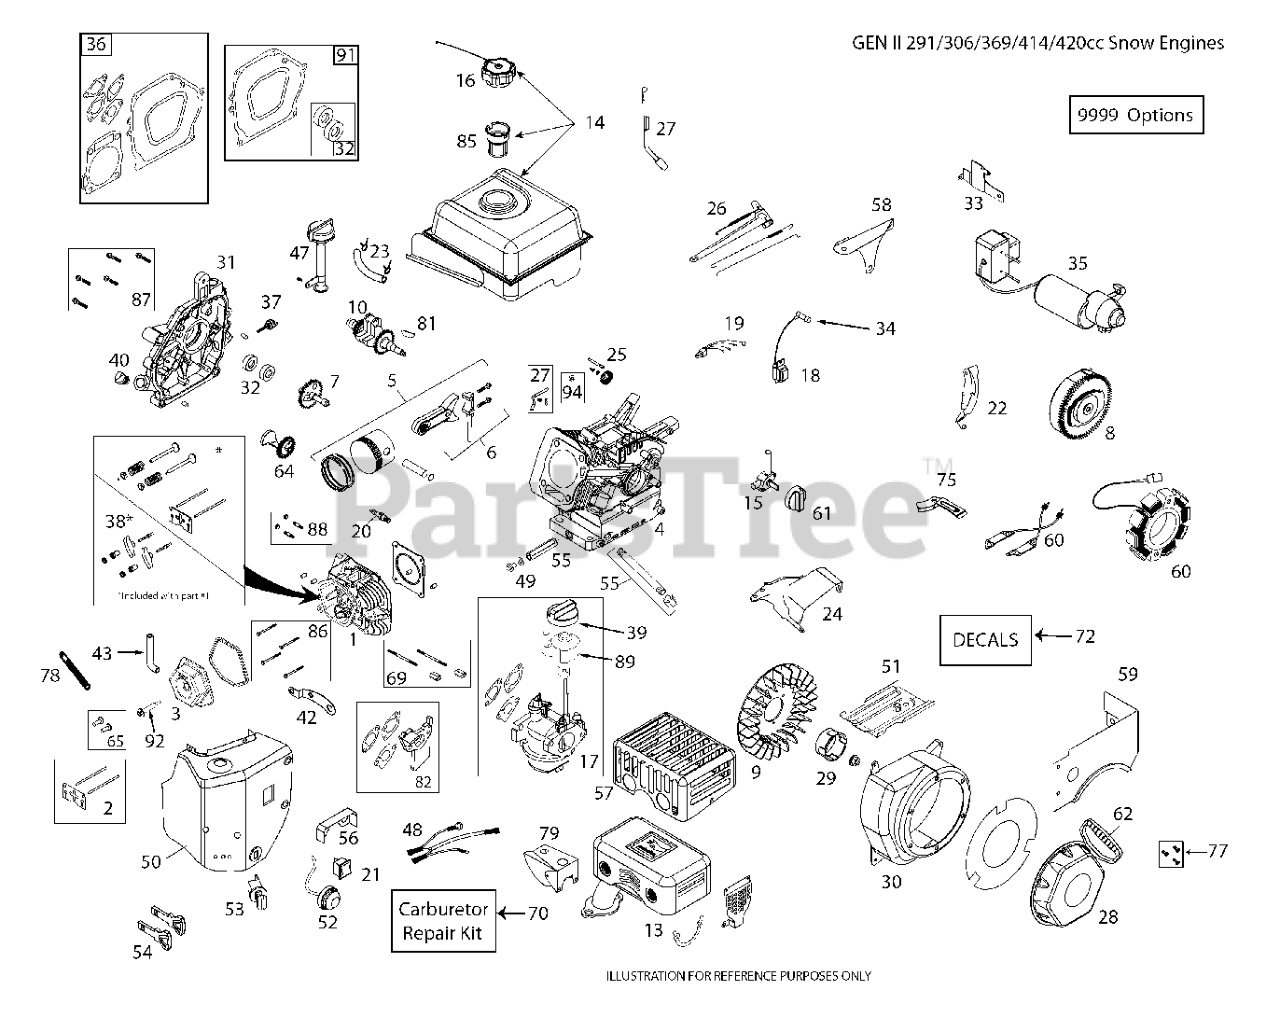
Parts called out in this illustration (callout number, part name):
2	SQUARE KEY
15	WASHER
17	SPRING.BRAKE.K46.GREEN
26	SPRING.RETURN.CRUISE
29	ROD.BRAKE.K46
35	ROD .BRAKE. PARKING. GT. HUSQ.
42	PEDAL COVER T
50	IDLER.FLAT.910.OFFSET
51	NUT LOCK FLG 3/8-16 UNC
52	IDLER.V-GROOVE.910.OFFSET
56	V-BELT.MOWER.92.40.42/K46
64	SHAFT.ASM.PEDAL.BRK.CNTR
73	BOLT
92	BOLT
99	ROD.SPRING.BYPASS.K46.LT.Z
116	NUT LOCK HEX FLANGE 5/16-18
125	SCREW
143	Screw 5/16-18 x 1/2 Hex, Self Tapping 5/16-18 x 1/2
153	RETAINER M
159	COTTER PIN
160	RETAINER CLIP
161	SPRING, RETURN LT
163	ROD.CONTROL.K57R.K46
166	NUT.PUSH.625
167	LATCH.BRAKE.SPRING
170	KEEPER.CENTER SPAN.1.688
183	SPACER AXLE
184	RB HANDLE.PARKG.BRK.HUS/PRED
186	SPACER.RETAINER
187	WASHER 12/32X2X10GA
188	RP.LINK.CLUTCH.GROUND.DRIVE
189	BELLCRANK.GROUND.DRIVE.TEX.
190	KEEPER.BELLCRANK.DRIVE
196	SCREW 3/8-16X1
197	CLUTCH.ANTIROTATION.WIREFORM.
206	BRACKET.MOUNT.CRUISE.LATCH
207	LATCH.CONTROL.CRUISE
208	GEAR.SECTOR.CONTROL.CR
209	ROD.CONTROL.CRUISE.GT.
210	ROCKER.ASM.PEDAL.CONTR
211	BEARING.NYLON
213	KNOB.CONTROL.CRUSIE.HU
214	PEDAL.FORWARD.PAD.TEX
215	PEDAL.REVERSE.TEX.GT.4
216	BRACKET.PULLEY.IDLER.W/TEX
221	RETAINER.SPRING.CLIP.H
222	WASHER 21/32 X 1-1/4 X 10 GA.
225	KEEPER.BELT.TRANSAXLE.K46
227	SCREW.THDROL.5/16-18X3/4.TTY
230	WASHER.HARDENED
231	IDLER.V-GROOVE.1.688.OFFSET
325	TORQUE.STRAP.K46.LT.LH
326	BRACKET.TRQ.STP.K46.18"TIRE.RH
334	SWAY.ROD.BRACKET.K46.X431
336	BOLT.5/16-18X1-3/4.FLANGED.HEX
